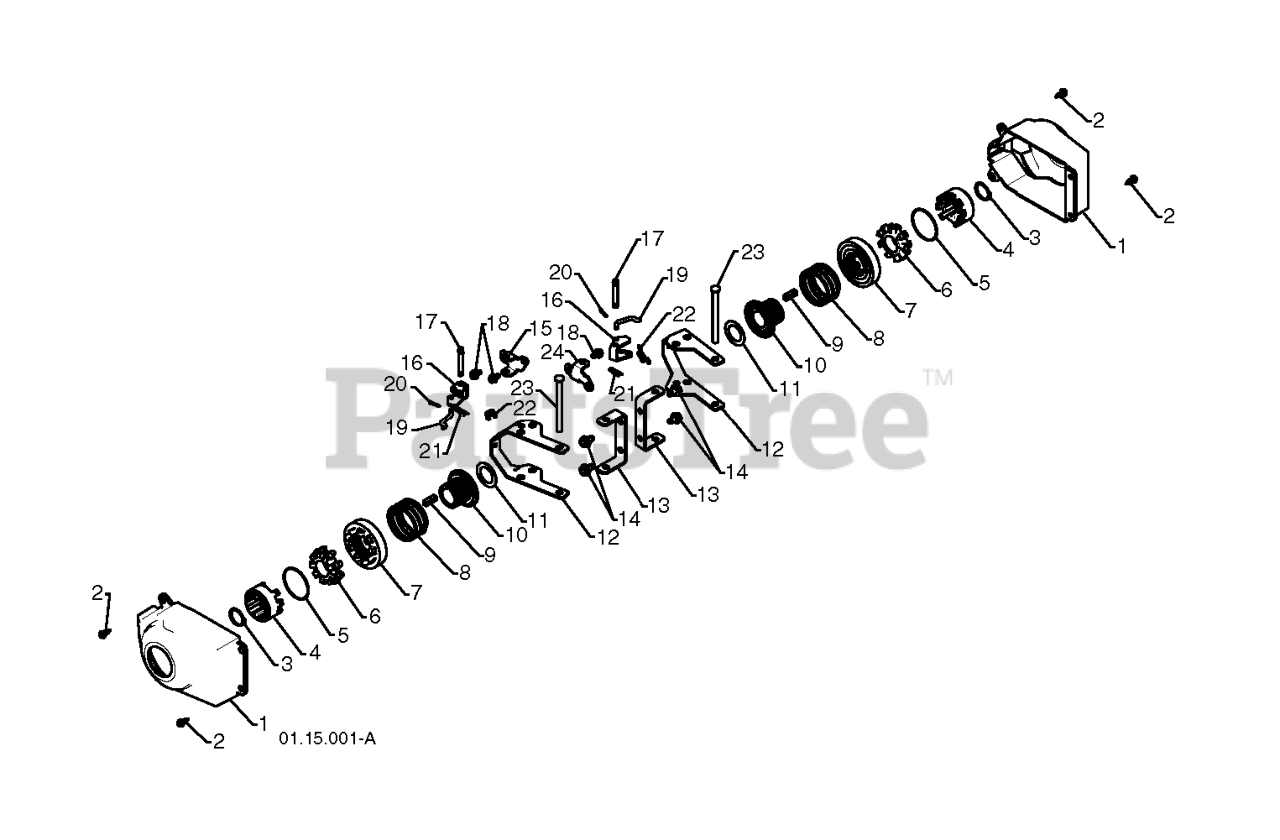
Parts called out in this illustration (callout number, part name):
1	COVER, POWER STEERING
2	SCREW, HEX HEAD, TAPPING
4	RP.DRIVER WHEEL
5	RING, WIRE RETAINER
6	LOBE WHEEL
7	RP.SLIDE.CLUTCH
8	SPRING, CLUTCH SLIDE
9	KEY, SQUARE 1/4 X .875
10	RP.LOBE.AXLE
11	WASHER TRUST 1"
12	YOKE.PNT.WELDMENT.STEE
13	BRACKET
14	Screw 5/16-18 x 1/2 Hex, Self Tapping 5/16-18 x 1/2
15	BRKT.STEER.PIVOT.RH
16	BELLCRANK.STEER
17	PIN, STEERING BELLCRANK
18	SCREW 1/4X20
19	LINK.STEER.YOKE
20	RETAINER CLIP
21	RETAINER CLIP PM
22	SPRING LATCH
23	PIN, STEERING LEVER
24	BRACKET.STEER.PIVOT.LH.YZ
